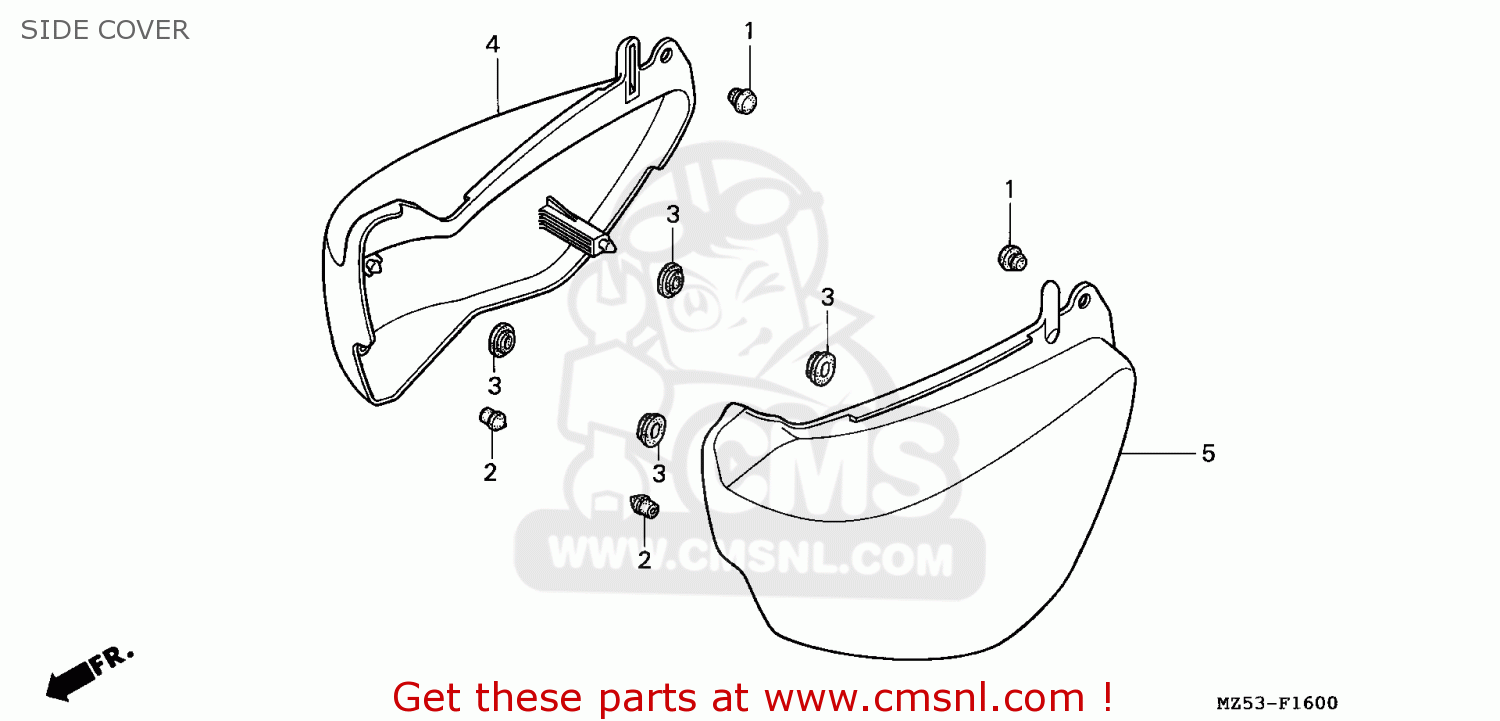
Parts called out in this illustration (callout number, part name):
1	RUB B,STOPPER
2	CAP,STEP HOLDER E
3	CASE,GROMET
4	COVER,R SID*R201*
5	COVER,L SID*R201*
